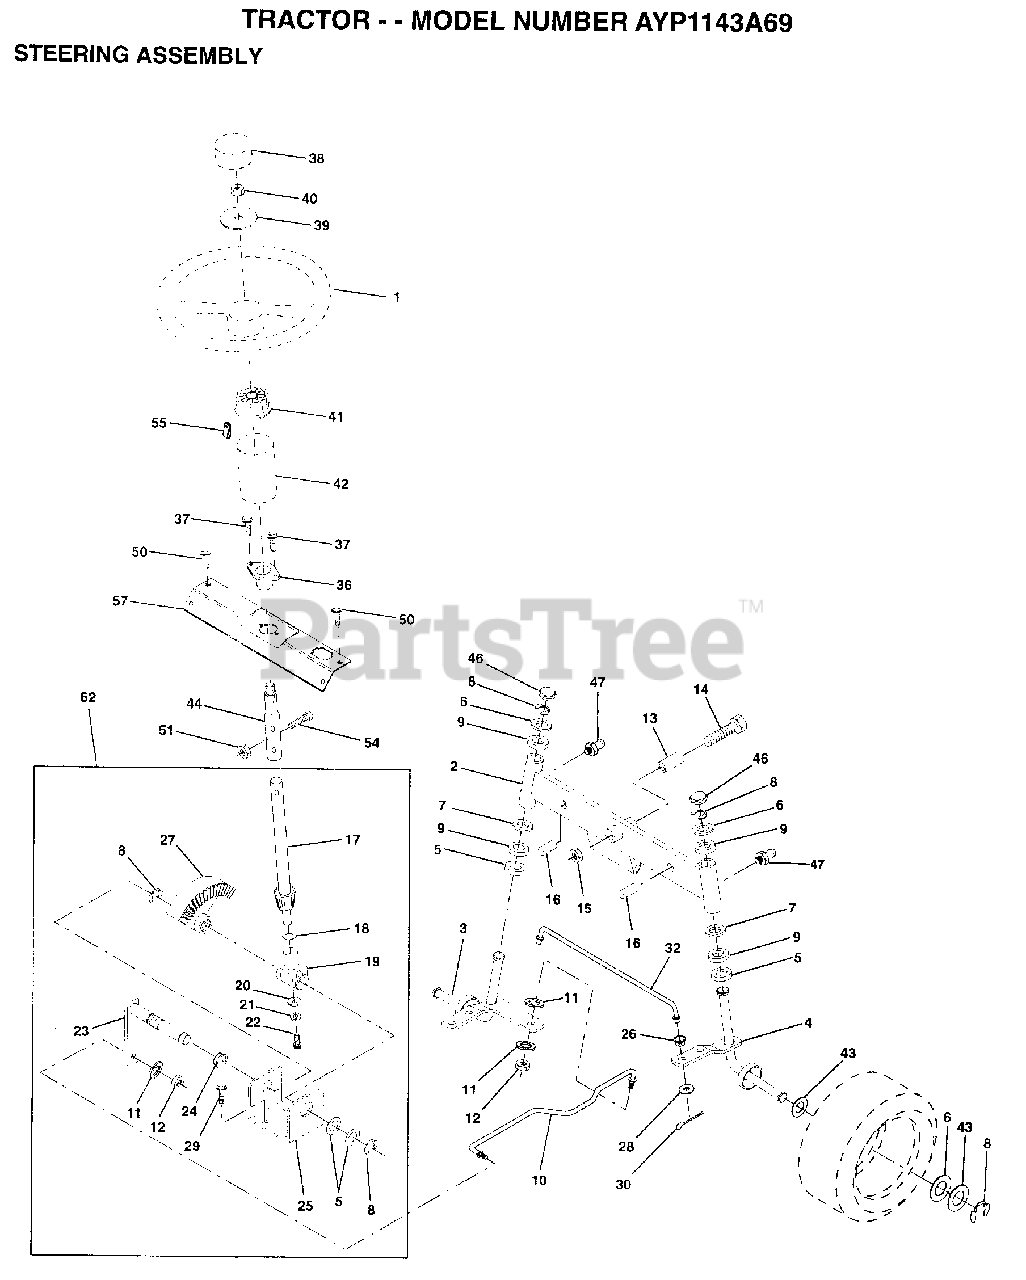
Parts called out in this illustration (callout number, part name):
1	WHEEL STR AYP BLK
2	AXLE ASM FRONT
3	SPINDLE LH
4	SPINDLE RH
5	WASHER .T
6	WASHER
7	WASHER
8	RING
9	COL. SRTG. BEAR.
11	LOCKWASHER
13	BEARING
14	BOLT HEX 5/8-11
15	"NUT-LOC,FLANGE LT"
16	AXLE PIN
17	SHAFT ASM STEERIN
18	THRUST WASHER
19	SUPPORT.SHAFT
21	LOCKWASHER
22	SCREW.SCKTHD.CAP
24	NYLINER T
25	"BRKT,STEERING"
26	BUSHING.DRAGLINK
27	GEAR SECTOR
28	WASHER
29	SCREW
30	COTTER PIN
32	TIE ROD
38	CAP STEER AYP
39	WASHER T
40	GRIPCO NUT
41	ADAPTER-WHEEL LT
42	BOOT SHAFT STEER
43	WASHER
46	CAP
47	ZERK M
50	SCREW HEX CRT
51	NUT
54	BOLT
55	CLIP TINNERMAN
57	SUPPORT SHAFT STR
